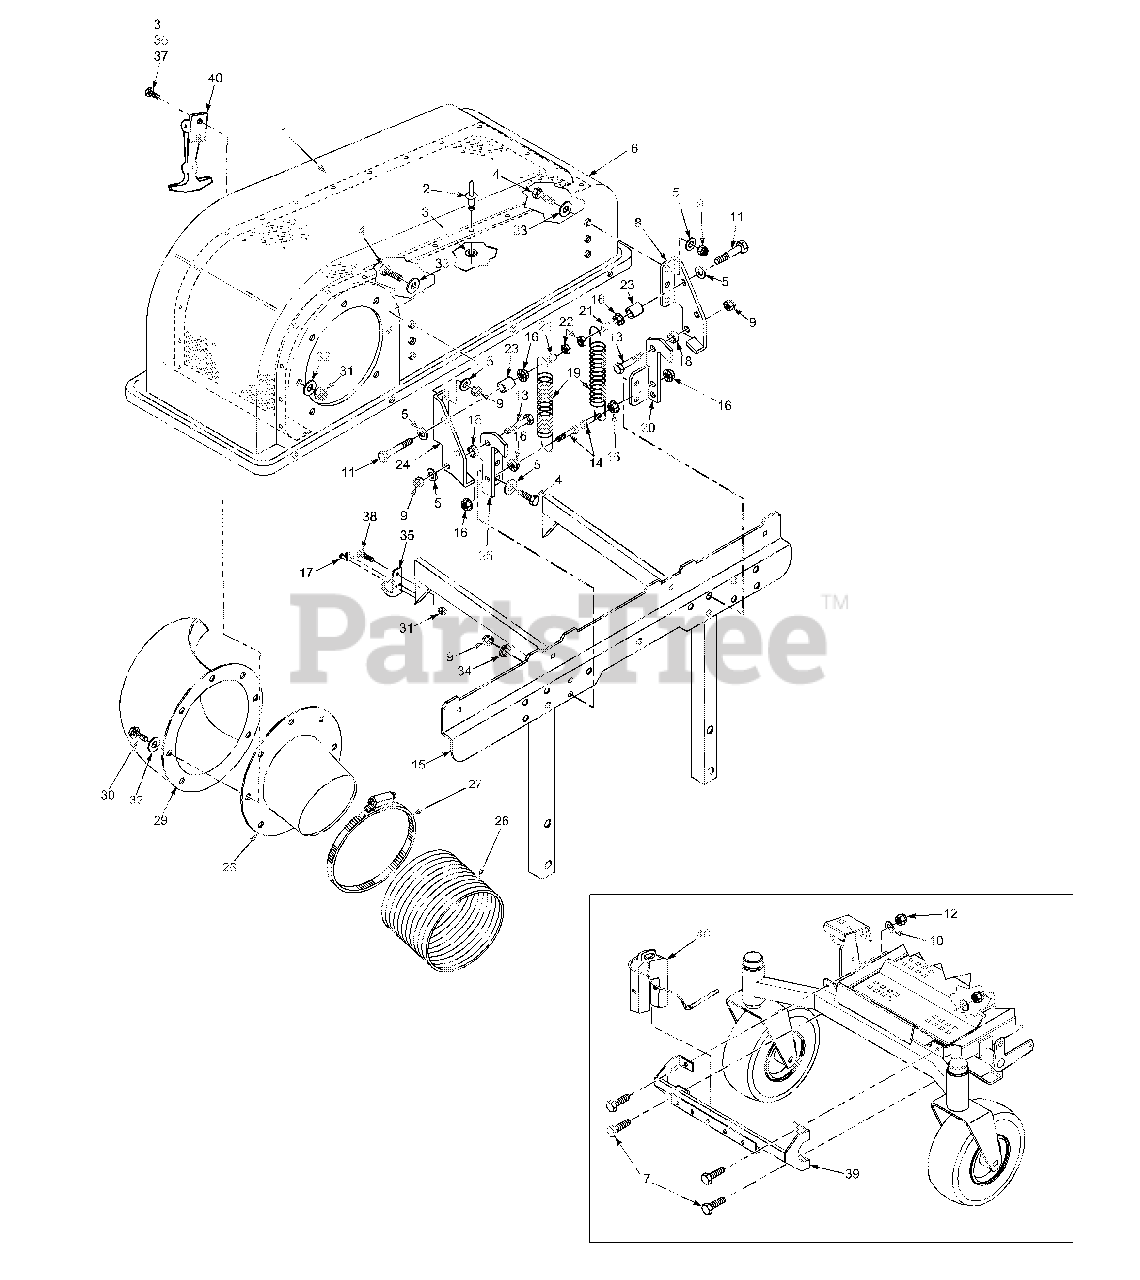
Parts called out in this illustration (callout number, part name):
1	Screen, Catcher Hood
2	Pop Rivet, 3/16 x .652
3	Flatwasher, 3/16-.196 x .469 x .048
4	Bolt, Hex Head 3/8-16 x 1-1/4"
5	Flatwasher, 3/8-.391 x .938 x .105
6	Hood Assembly, GC-STT
7	Bolt, Hex Head 7/16-14 x 1-3/4"
8	Hinge, Upper LH
9	Nut, Elastic Stop 3/8-16
10	Flatwasher, 7/16-.500 x 1-1/4"
11	Bolt, Hex Head 3/8-16 x 2-1/4"
12	Nut, Elastic Stop 7/16-14
13	Bolt, Hex Head 3/8-16 x 1-1/2"
14	Bolt, Hex Head 3/8-16 x 1-3/4" Grade 8
15	Support Weldment, Bag Frame
16	Nut, Serrated Flange 3/8-16
17	Rivot, 3/16 x .402 POP
18	Bushing, Hopper Pivot
19	Spring, Hood Hinge
20	Hinge, Lower LH
21	Spacer
22	Locknut, 3/8-16
23	Spacer
24	Hinge, Upper RH
25	Hinge, Lower RH
26	Hose, 6" Dia. x 49.5"
27	Clamp, 6-1/2" Max Dia.
28	Tube, Filler GC-STC
29	Elbow, GC-STC
30	Bolt, Hex Head 5/16-18 x 1-1/4"
31	Nut, Elastic Stop 5/16-18
32	Flatwasher, 5/16-.375 x .875 x .083
33	Flatwasher, 3/8- .406 x 1-1/2" x .179
34	Lockwasher, 3/8 Spring
35	Latch
36	Screw, #10-32 x 3/4"
37	Nut, Elastic Stop #10-32
38	Bolt, Hex Head 5/16-18 x 3/4"
39	Support Weldment, Weight
40	Weight Assembly
